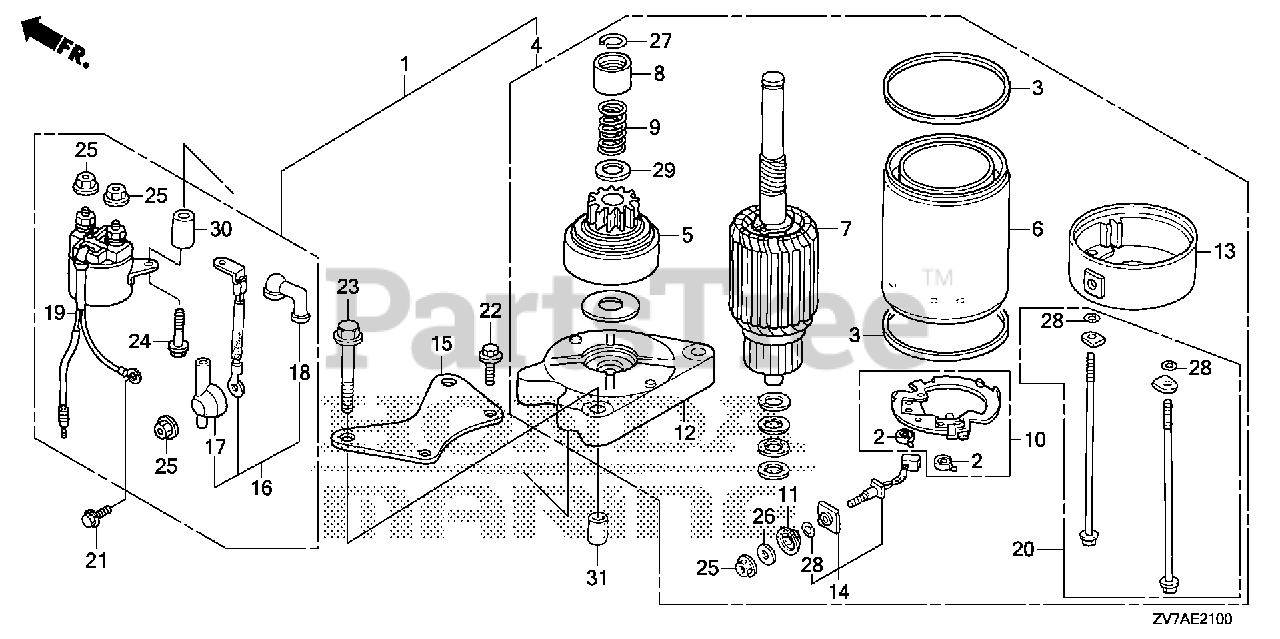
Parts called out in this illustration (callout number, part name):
1	STARTER MOTOR ASSY.
2	SPRING, CARBON BRUSH
4	STARTER MOTOR UNIT
8	PIECE, STOPPER
9	SPRING, RETURN
10	HOLDER, BRUSH
12	BRACKET, FR.
13	BRACKET, RR.
14	TERMINAL UNIT
15	STAY, STARTER MOTOR
16	WIRE, MAGNETIC SWITCH
17	COVER, STARTER TERMINAL
18	COVER, MAGNETIC SWITCH TERMINAL
19	SWITCH ASSY., STARTER MAGNETIC
20	BOLT SET, SETTING
21	BOLT, FLANGE (6X12) (CT200)
22	BOLT, FLANGE (6X16)
23	BOLT, FLANGE (8X45)
24	BOLT, FLANGE (6X25)
25	NUT-WASHER (6MM)
26	WASHER (6MM)
27	CIRCLIP (14MM)
28	O-RING (4X2)
30	COLLAR, DISTANCE
31	PIN, DOWEL (10X16)
